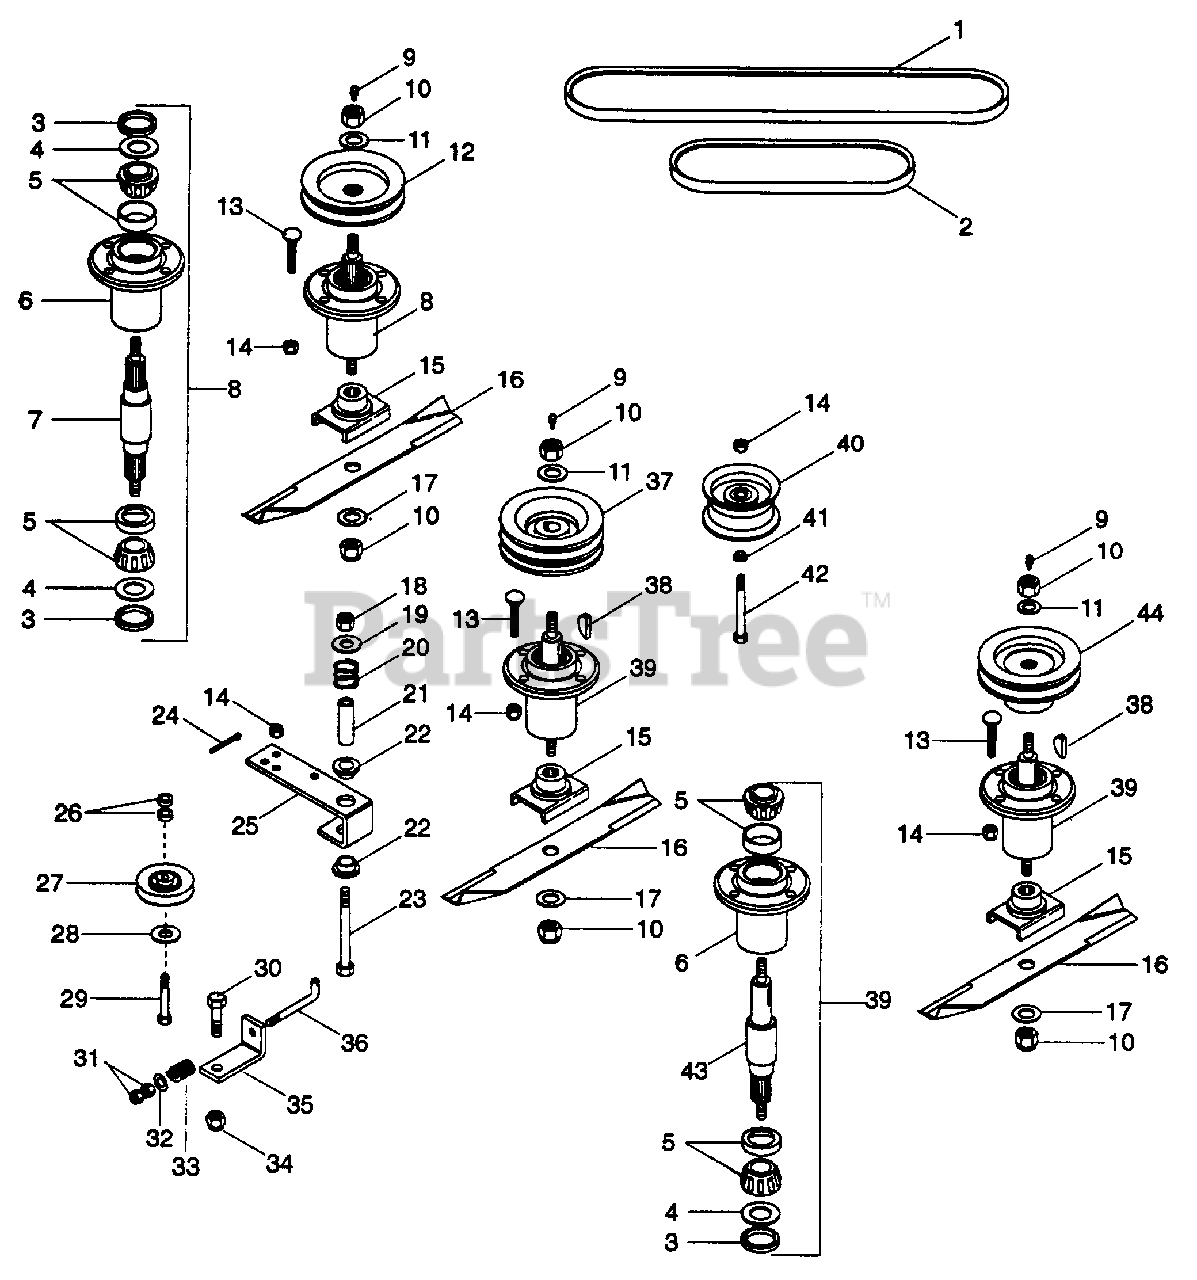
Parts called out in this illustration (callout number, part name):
1	V-BELT A-RMA 37.8 X 33/64
2	V-BELT A-RMA 18.05 X .495
3	SL, STEEL(LEFT & CENTER SPINDLES)
3	SL, STEEL(RIGHT SPINDLE)
4	WSHR-FL-STL .97 X 1.865 X .03
5	ASM, BEARING CUP & CONE
6	HSG, BEARING
7	SHFT, SPINDLE
8	SPNDL, ASSEMBLY
9	FTG, LUBE 1/8
10	NUT-LK-NYL .625-11 PL
11	WSHR-FL-STL .687 X 1.312 X .135
12	SHEAVE, SPLINED SPINDLE, FAB'D
13	BLT-RDHDSQNK .38-16 X 1.375
14	NUT-LK-NYL .375-16 PL
15	WLDMT, BLADE CRDL
16	BLD
17	WHSR-FL-STL .656 X 1.312 X .095 PL
18	NUT-LK .50-13 HEX TYPE N
19	WSHR-FL-STL .531 X 1.250 X .100
20	SG-COMP .085 X 1.00 WLD 36
21	BUSH., S .560 X .750 X 2.44 ST
22	BSHG-FLG .762 X 1.0 X .580 X 1.48 NY
23	BLT-HEX .50-13 X 3.50 PL GR 5
24	PIN-COTR .09 X .75 PL
25	ARM, IDLER PIVOT
26	BUSHING .406 X .750 X .188
27	IDLER-V 3 X .38
28	WSHR-FL-STL .375 X 1.125 X .065
29	BLT-HEX .38-16 X 2.00 PL GR 5
30	BLT-HEX .50-13 X 1.25 PL GR 5
31	NUT-HEX .375-16
32	WSHR-FL-STL .406 X .812 X .065
33	SG-COMP .125 X .78 X 1.00
34	NUT-LK-NYL .50-13 PL
35	BRKT, BELT TENSIONER
36	ROD, IDLER
37	SHEAVE, CENTER SPINDLE, FAB'D
38	KEY, WDRF .25 X 1 HRD #15
39	ASM, SPINDLE
40	PLY-FLAT 4.0 X .38 N HAMSHR
41	BSHG-SLV .377 X .503 X .88
42	BLT-HEX .38-16 X 3.00 PL GR 5
43	SHAFT, SPINDLE
44	SPINDLE SHEAVE
NS	BELT FINGER, PRO 150 DECK
